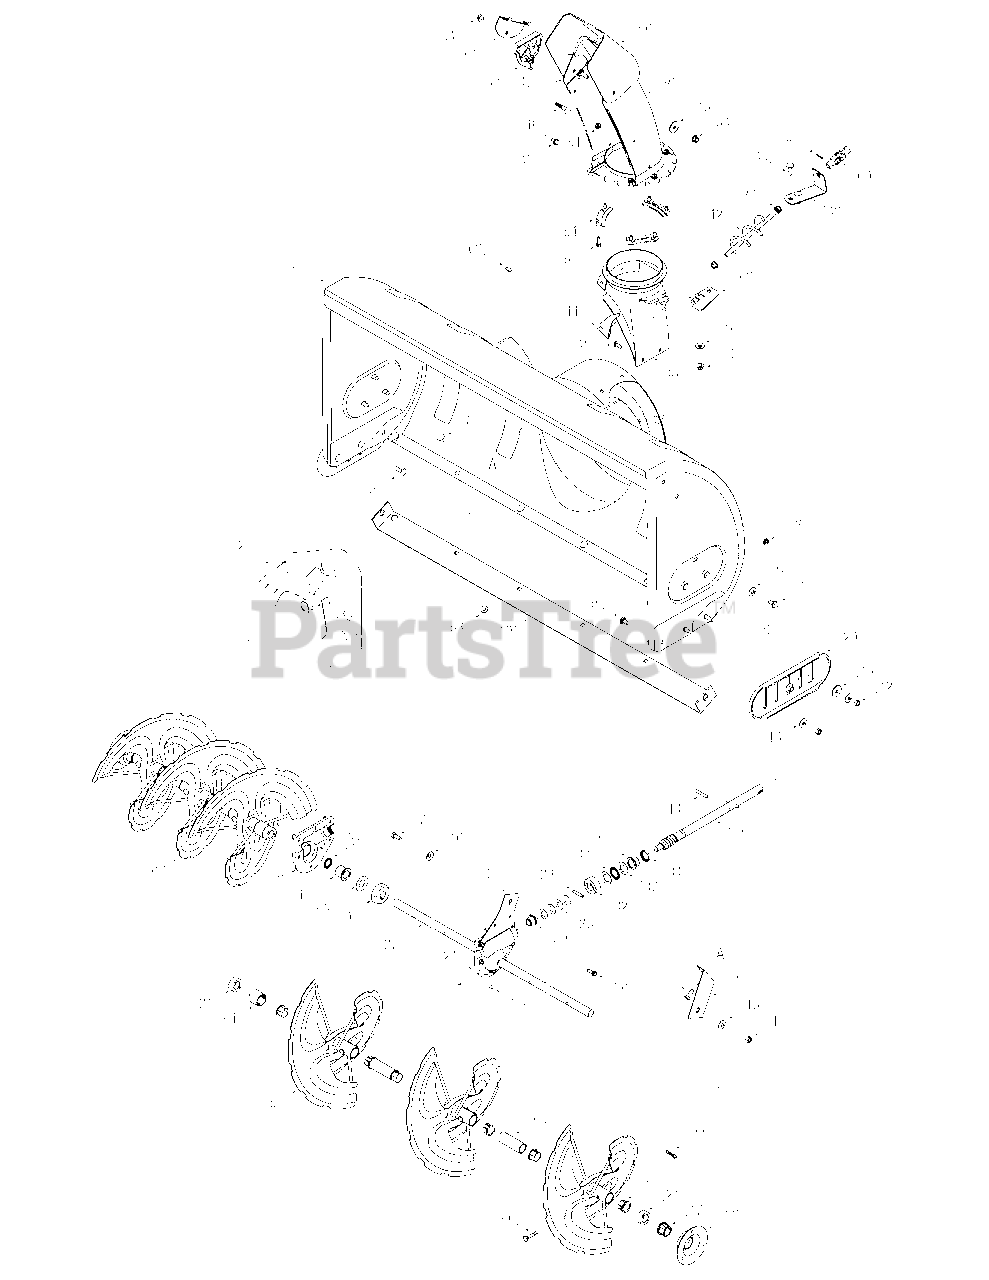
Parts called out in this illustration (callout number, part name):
1	Auger Gear Box (Incl. Ref. 23-41)
7	Hex Cap Screw, 5/16-24 x .75
8	Carriage Bolt, 5/16-18 x .62
9	Splined Carriage Screw
10	Self Tapping Screw
11	Bow-Tie Cotter Pin
12	HEX NUT 5/16-18
13	Hex Nut, 5/16-24
14	Spirol Pin, 1/4 x 1-1/2
15	Flat Washer, .344 x 1.125 x.12
16	Bell Washer, .340 x .872
17	Hex Flange Bearing, .75 ID
18	Flange Bushing, .80 x .91
21	Spacer, .75 x .125 x .5
23	RH Reducer Housing
24	LH Reducer Housing
26	Self Tapping Screw, 1/4-20 x .75
27	Spiral Axle, 41.5"
28	Hi-Pro Key, 3/16 x 5/8
29	Spring Spirol Pin, .25 x 1.25
30	Worm Gear, 20-tooth
31	Worm Shaft
32	Thrust Collar
33	Grease Plug
34	Grease Seal
35	Flat Washer, .76 x 1.5 x
36	Flat Washer, .508 x 1.0 x .020
37	Thrust Washer, .75 x 1.25 x .0615
38	Thrust Bearing, .75 x 1.25 x .078
39	Flange Bearing, .503 x .75
40	Flange Bearing, .75 x 1.0 x .59
41	Grease Seal
42	Chute Crank Assembly
45	Splined Carriage Screw
46	Carriage Bolt, 5/16-18 x 1.5
47	Carriage Screw, 5/16-18 x 1.0
48	Screw, 1/4-20 x .75
49	Hex Index Washer Screw
50	Hex Cap Screw, 1/4-20 x .75
51	Nylon Hex Lock Nut, 1/4 x 20
52	Nylon Hex Lock Nut, 5/16-18
53	Spirol Pin, .125 x .82
54	Chute Flange Keeper
55	Lower Chute
56	Upper Chute
57	Adapter Chute
58	Chute Tilt Cable Guide
59	Plastic Bushing
60	Joint Block Assembly
63	HEX FLANGE NUT
64	Spacer 1.25 x .75 x 1.00
65	Sleeve .758 x 1.00 x 2.70
66	Shear Pin, .25 x 1.50
